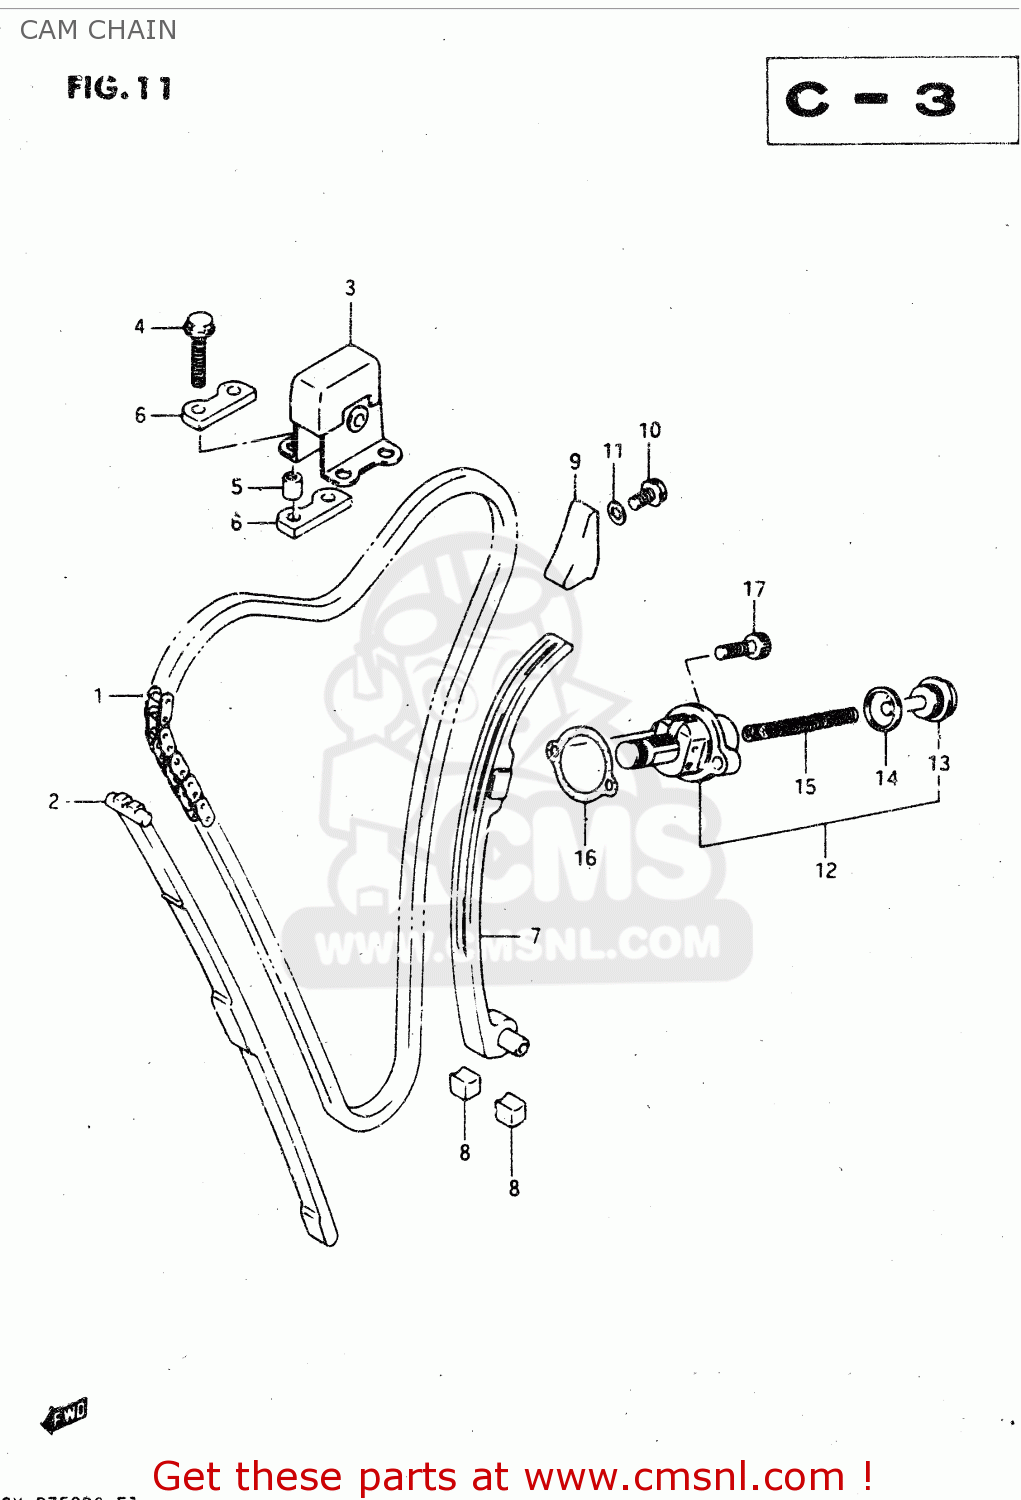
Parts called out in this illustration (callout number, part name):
1	CHAIN,CAMSHAFT DRIVE
2	GUIDE,CAM CHAIN NO.1
3	IDLER,CAM CHAIN
4	BOLT
5	SPACER
6	GUIDE,CAM CHAIN
7	TENSIONER,CAM CHAIN
8	CUSHION,CAM CHAIN TENSIONER
9	GUIDE,CAM CHAIN NO.2
10	BOLT
11	GASKET(5.8X13X1.2) (NAS)
12	ADJUSTER ASSEMBLY,TENSIONER
13	PLUG
14	GASKET (NAS)
15	SPRING
16	GASKET,TENSIONER ADJUSTER (NAS)
17	BOLT
